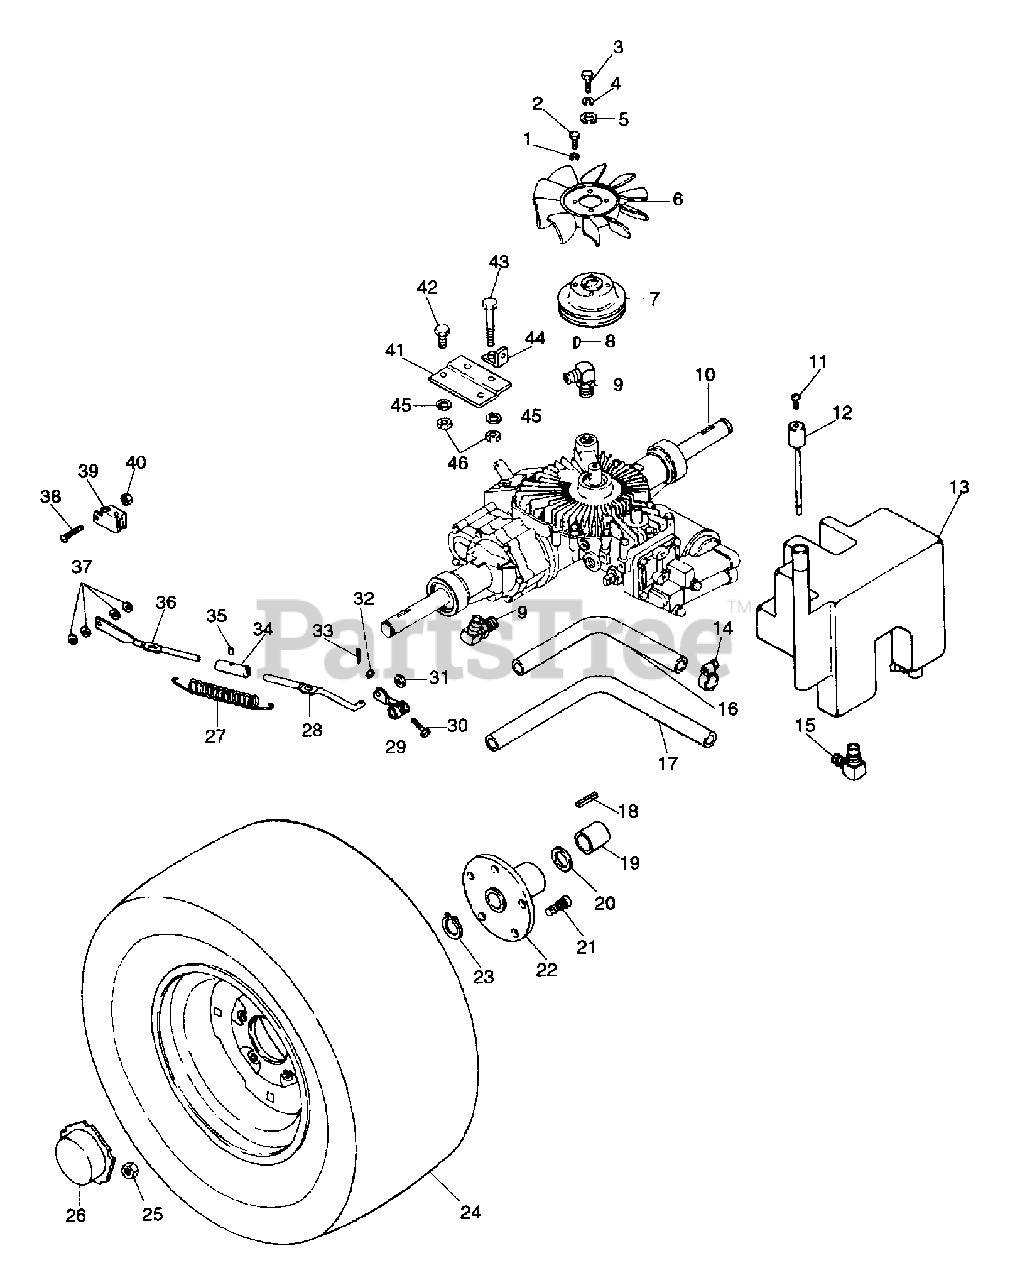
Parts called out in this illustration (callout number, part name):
1	WSHR-LK-EXT #10 ID X .022
2	BLT-HEX 10-24X.38 PL GR2
3	BLT-HEX .25-20X1.00 PL GR5
4	WSHR-LK .250X.077 HVY PL
5	WSHR-FL-STL .265X1.370X.145
7	SHEAVE - TRANSAXLE
8	KEY-WDRF .188X.625X.25 SAE 61
9	FITTING
10	TRANSAXLE
10	TRANSAXLE - HYDRO
11	SCR-VENT SL 8-32X.250
12	DIP STICK
13	OIL RESERVOIR
14	CLAMP-HOSE WRM .38/.62X.50 #10
15	HOSE FITTING
18	KEY-STR .25X2.0X.25
19	SPACER 1.006X1.437X1.928
20	WSHR-FL-STL 1.010X1.505X.062PL
21	BLT-LUG SERNKHDND .44-20X1.188
22	WHEEL HUB
23	RG-RTNG-EXT 1.00X.078
24	WHL
24	T/WHL ASSY 10.50X23
24	TIRE
24	WHL 12X8.50
24	T/WHL ASSY
25	NUT-LUG .437-20 YWZC
26	REAR HUB CAP
27	SG-TENS .090X.96X4.0 WLD 23
29	ARM-DUMP VALVE
30	BLT-HEX .25-20X1.00 GR2
31	WSHR-FL-STL.344X.688X.065PL
32	NUT-LK-CTR .250-20 PL
33	PIN-COTR .09X.75 PL
34	COLLAR .380X.625X2.00
35	PIN-ROLL .125X.63
37	WSHR-FL-STL.281X.62X.065 PL
38	SCR-MCH 10-24X.88 SLRH PL
40	NUT-LK TOP 10-24 PL
41	BRACKET
42	BLT-HEX .38-16X1.00 PL GR5
43	BLT-HEX .38-16X3.25 PL GR5
44	SPRING ANCHOR
45	WSHR-FL-STL .390X.750X.125 PL
46	NUT-LK TOP .375-16 GR C YWZC
